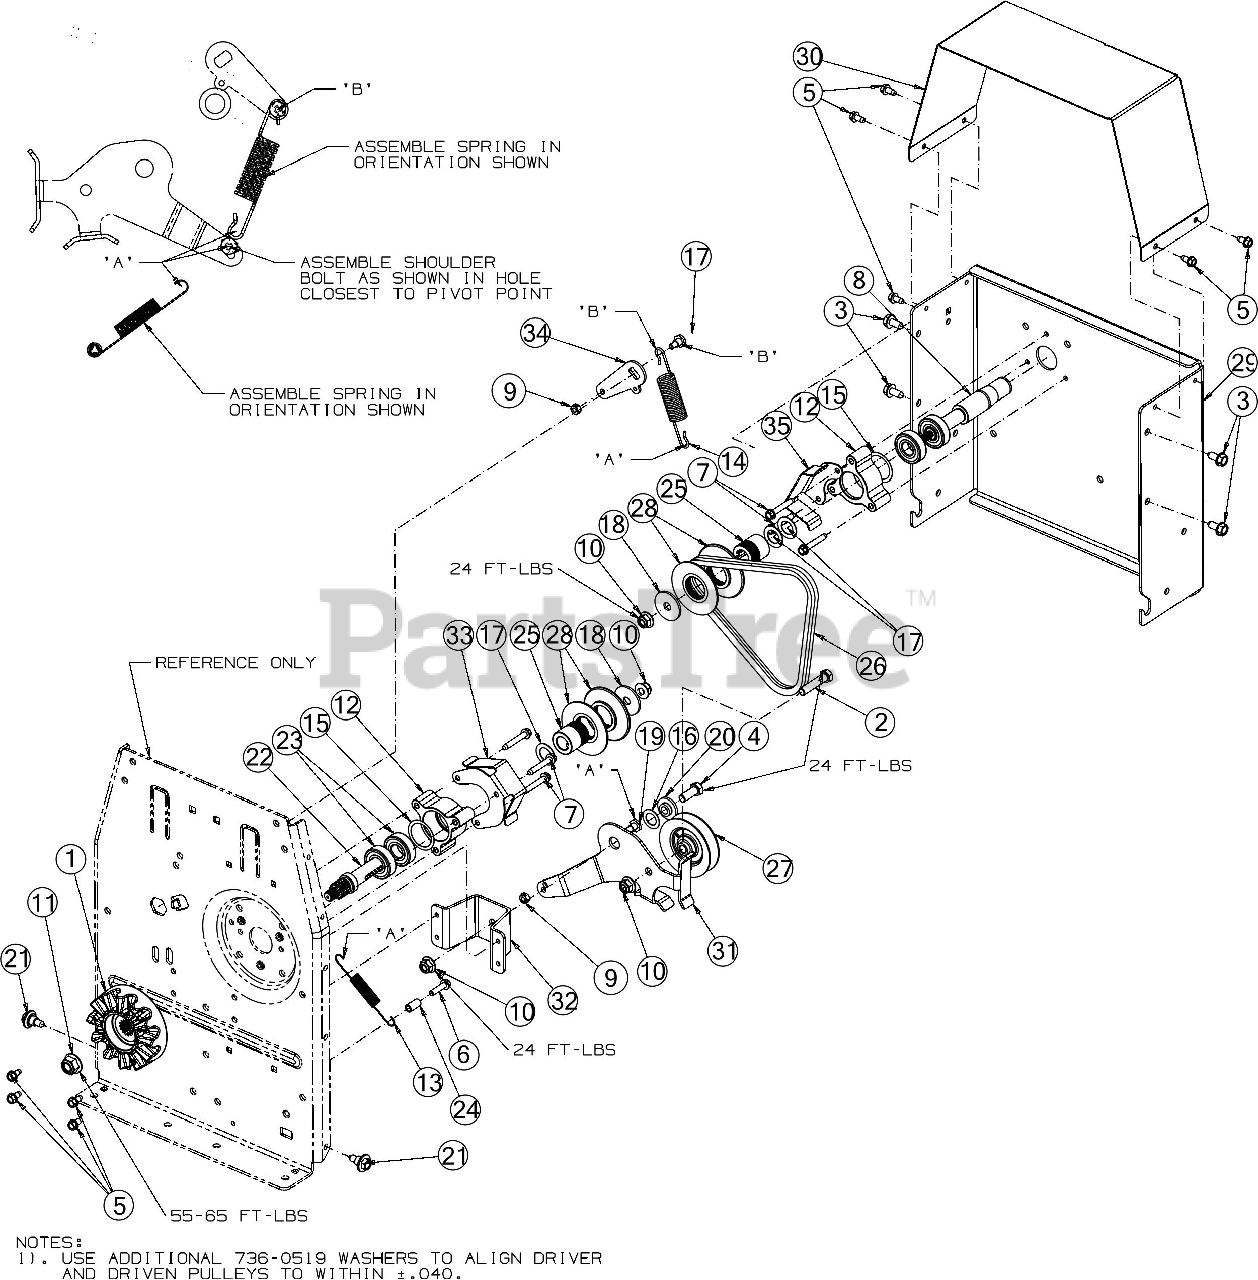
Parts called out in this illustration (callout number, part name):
1	DOG CLUTCH BUMPER
1	DOG CLUTCH
1	DOG CLUTCH ASSEMBLY
2	HEX SCREW 3/8-16 x 1.75 GR5
3	SCREW 5/16-18 x .750
4	SCREW 3/8-16 x 1 GR5
5	SCREW 1/4-20 X.500
6	SCREW 1/4-20 x 1.00
7	SCREW 1/4-20 X1.625
8	SPINDLE SHAFT
9	HEX NUT
12	BEARING CUP
13	EXTENSION SPRING
14	EXTENSION SPRING.85 ODX 5.026
15	SHIM WASHER
16	THRUST WASHER
17	THRUST WASHER
18	FLAT WASHER .406X1.500X.105
19	SHOULDER SCREW .340
20	SHOULDER SPACER
21	SHOULDER SCREW .43X.29X5/16-18 TT
22	DRIVE SPINDLE
23	BALL BEARING
24	SPACER .260 x .375 x .75
25	SPACER-.670ID x 1.185
26	V-BELT 4L:24.82 ARAMID
27	V-IDLER PULLEY A x 3.06 OD
28	HALF PULLEY
30	TOP COVER BRACKET
31	IDLER BRACKET
32	IDLER BRACKET MOUNT
33	KEEPER BRACKET
34	ENGAGEMENT CABLE BRACKET
35	KEEPER BRACKET
